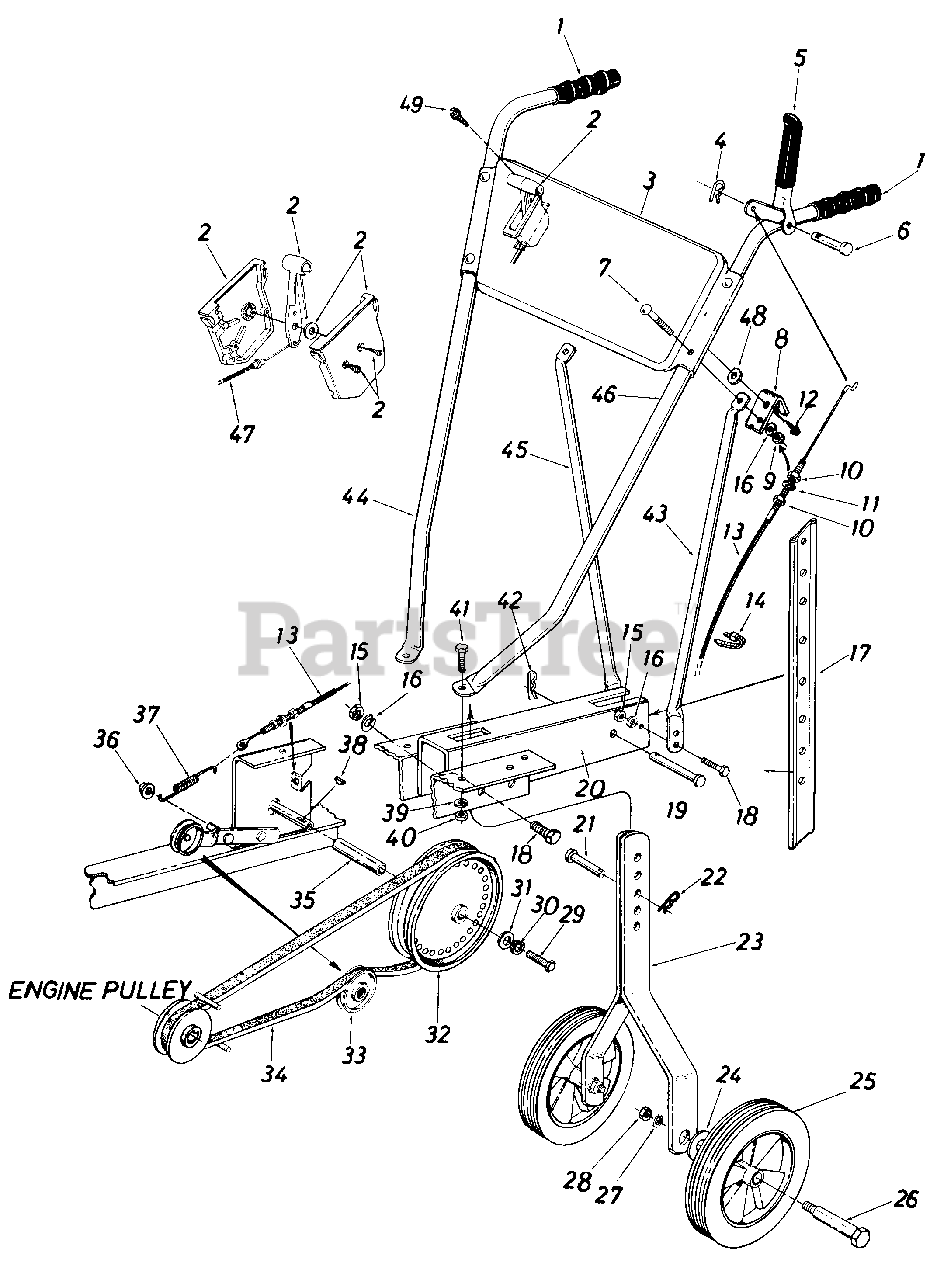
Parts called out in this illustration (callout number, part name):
2	Throttle Control Box
4	Int. Cotter Pin
5	Clutch Grip Ass'y.
7	Carriage Bolt 5/16-18 x 1.75" Lg.
8	Cable Support Brkt.
9	Hex Nut 5/16-18 Thd.
10	Hex Jam Nut 5/16-24 Thd.
11	L-Wash. 5/16" I.D.*
12	Hex Wash. Hd. Self-Tap Scr. 1/4-20 x .50" Lg.
13	Clutch Control Cable
15	Hex Nut 5/16-18 Thd.
16	L-Wash. 5/16" I.D.
18	Hex Bolt 5/16-18 x .75" Lg.
19	Clevis Pin 1/2" Dia. x 2 50n Lg.
20	Tailpiece Ass'y.
21	Clevis Pin 3/8" Dia. x 2.50" Lg.
22	Hairpin Cotter
23	Wheel Bracket Ass'y.
24	Belleville Wash. 1/2" I.D.
25	Wheel Ass'y. Comp.-Plastic
26	Shoulder Bolt
27	L-Wash. 1/2" I.D.
28	Hex Nut 1/2-20 Thd.
29	Hex Bolt 1/4-28 x .75" Lg.
30	L-Wash. 1/4" I.D.
31	Fl-Wash. .25" I.D. x .930" O.D.
32	Pulley 6.00" O.D.
33	Idler Pulley
34	"V"-Belt 1/2" Pitch x 39" Lg.
36	Cap Speed Nut
37	Extension Spring
38	Hi-Pro Key
39	L-Wash. 5/16" I.D.
40	Hex Nut 5/16-18 Thd.
41	Hex Bolt 5/16-18 x 75" Lg.
42	Hairpin Cotter
43	Handle Support Bracket-L.H.
44	Handle Bar-R.H.
45	Handle Support Bracket-R.H.
46	Handle Bar-L.H.
47	Throttle Control Cable-35"
48	Fl-Wash. .281" I.D. x .50" O.D.
49	Self-Tap Scr. #10 x 1/2" Lg.
